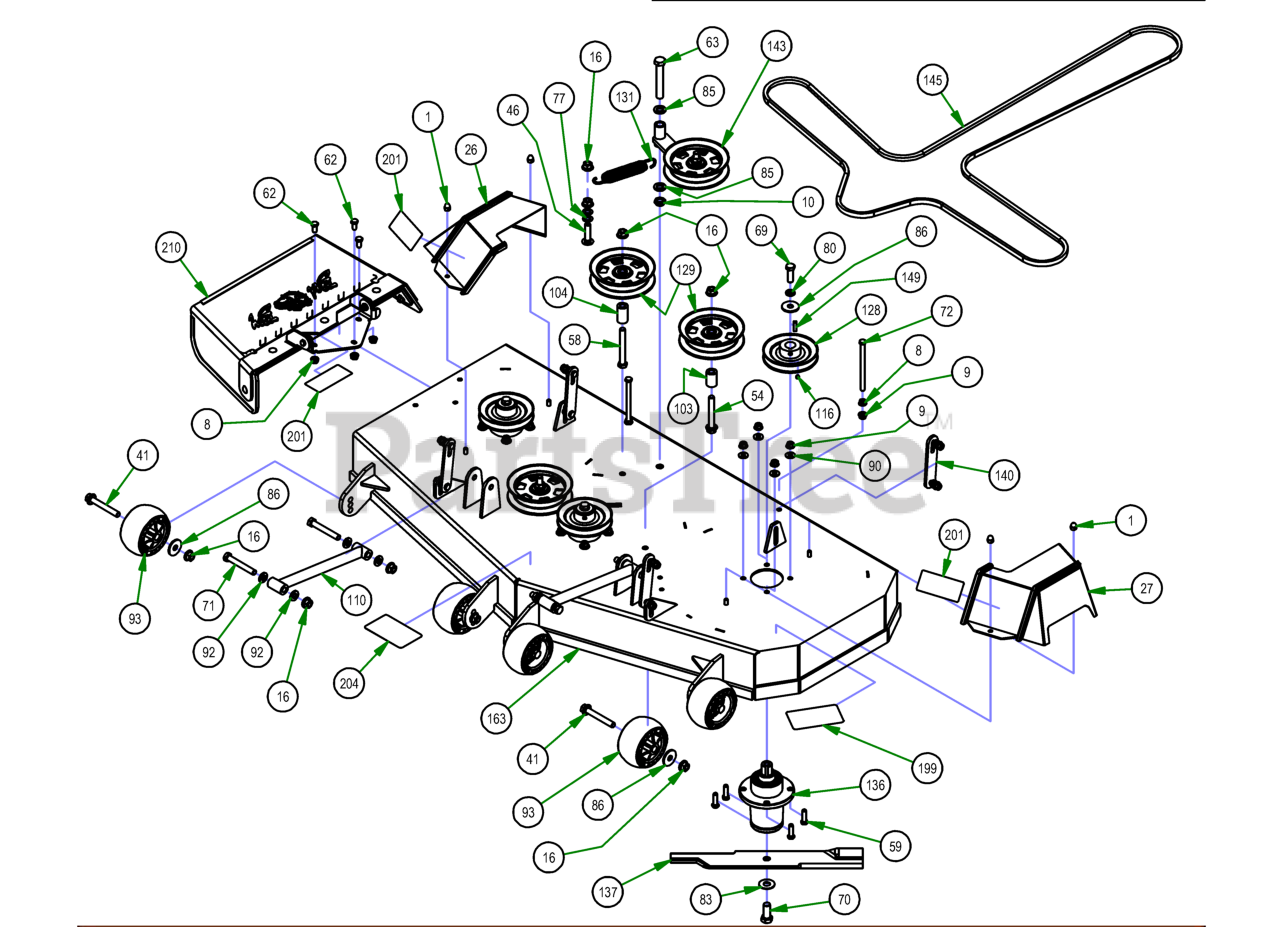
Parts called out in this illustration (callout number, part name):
1	5/16-18 ACORN NUT HIGH-CROWN ZC
8	3/8-16 HEX SERRATED FLANGE NUT HARD/ZINC
9	3/8-16 NYLON INSERT FLANGE LOCKNUT (GR.F) ZINC
10	5/8-11 NYLON INSERT JAM LOCKNUT ZINC
16	1/2-13 NYLON INSERT FLANGE LOCKNUT ZINC
26	2021 Maverick 54”/60” RH Pulley Cover
27	2021 Maverick 54”/60” LH Pulley Cover
41	1/2-13 X 90MM HEX FLANGE BOLT W/SHOULDER (GR.8) ZINC
46	1/2-13 X 2 CARRIAGE BOLT ZINC
54	1/2-13 X 3-1/2 HEX FLANGE BOLT (GR.8) ZINC
58	1/2-13 X 4 HEX CAP SCREW (GR.8) ZINC YELLOW
59	3/8-16 X 1-1/4 HEX CAP SCREW (GR.5) ZINC
62	3/8-16 X 3/4 HEX CAP SCREW (GR.5) ZINC
63	5/8-11 X 4 HEX CAP SCREW (GR.8) ZINC YELLOW
69	1/2-20 X 1-1/2 HEX CAP SCREW (GR.5) ZINC
70	5/8-18 X 1-1/2 HEX CAP SCREW (GR.8) ZINC YELLOW
71	1/2-13 X 3-1/2 HEX CAP SCREW (GR.5) ZINC
72	3/8-16 X 5-1/2 HEX CAP SCREW (GR.5) ZINC
77	.517 SQ WDTH ID X .937 OD X .060 THICK F/W PHOS/OIL
80	1/2 SPLIT LOCKWASHER (GR.8) ZINC/YELLOW
83	5/8 USS FLAT WASHER (1-3/4" OD) GR.8 ZINC YELLOW
85	.635 ID X 1.120 OD X .140 THICK FLAT WASHER NYLON
86	1/2 BELLEVILLE WASHER (1-5/8 OD X .140 THK) ZINC
90	5/16 USS FLAT WASHER (7/8 OD) ZINC
92	.505 ID X 1.000 OD X .125 THICK FLAT WASHER NYLON
93	Deck Wheel
103	.502 ID X .750 OD X 1.500 Long Spacer
104	1 3/4" Pulley Spacer
110	MZ/ZT Deck Locator
116	5/16-24 X 1/4 SOCKET SET SCREW (CUP PT) PLAIN
128	5.25" Deck Spindle Pulley
129	5-3/4 Idler Pulley
131	Deck Idler Spring
136	Spindle Assembly
137	54" Fusion Blade for ZT/Mav/Outlaw/Revolt
140	Deck Hanger Assembly
143	2017 54"/48" Deck Idler Assembly
145	B155.75 Deck Belt
149	1/4 X 1 SQ MACHINERY KEY 1018 STL PLN
163	54 ZT Welded Deck
199	2018 54" Deck Decal
201	Danger Decal-Spindle/Discharge
204	Deck Belt Route Decal
210	Discharge Chute Assembly
